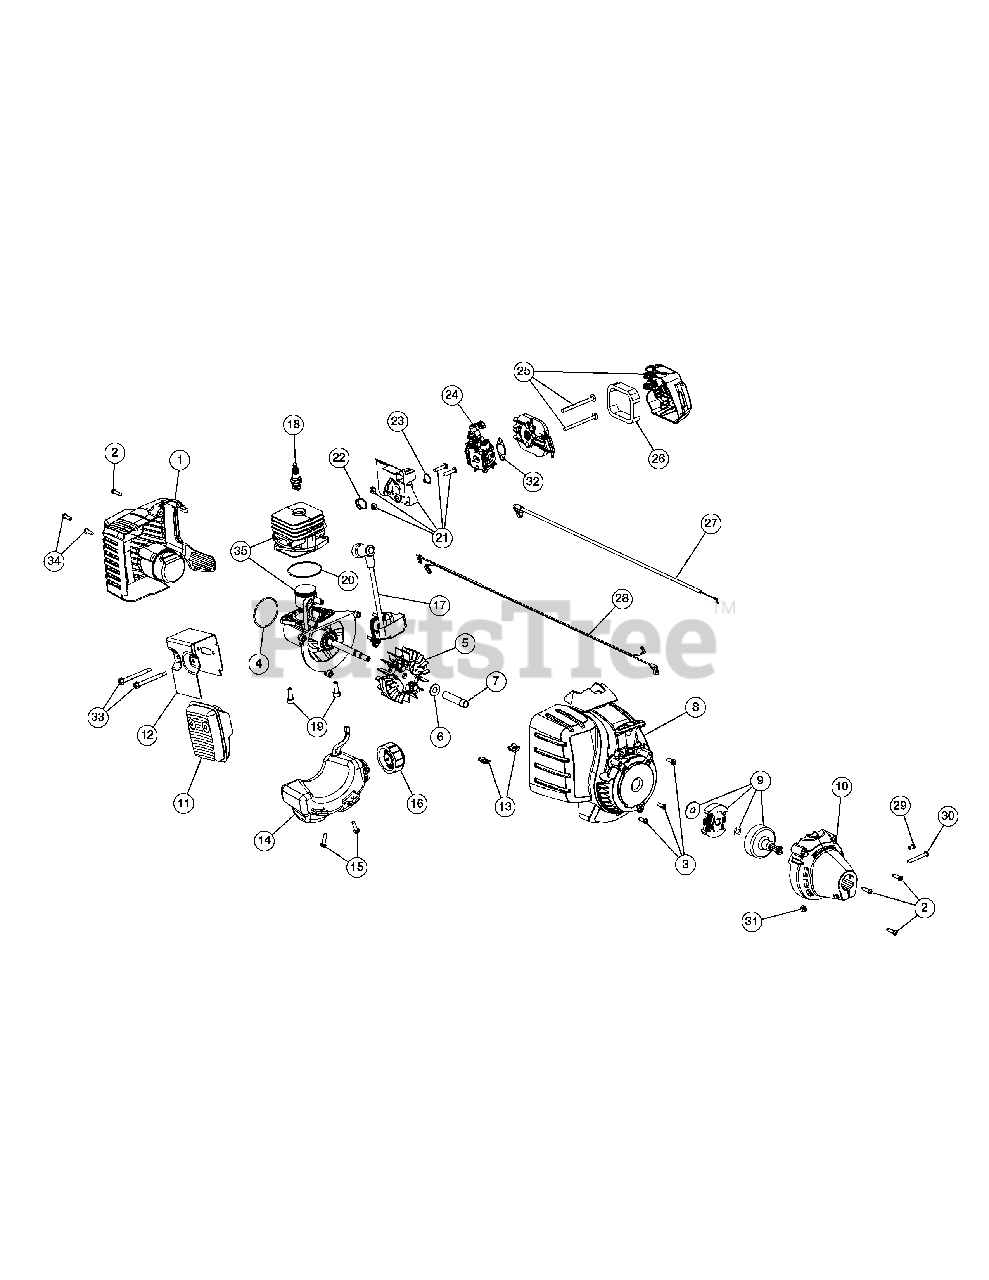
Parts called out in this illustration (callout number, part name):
1	Rear Cover Assembly (Incl. 2 & 34)
2	Cover Screw
3	Housing Screw
4	O-Ring
5	Flywheel Assembly
6	Washer
7	Spacer
8	Starter Housing (Incl. 3 & 13)
9	Clutch Assembly
10	Clutch Cover (Incl. 2)
11	Muffler Assembly (Incl. 12 & 33)
12	Muffler Gasket
13	U-shaped Nut
14	Fuel Tank Assembly (Incl. 15 & 16)
15	Tank Screw
16	Fuel Cap
17	Module Assembly
18	Spark Plug
19	Crankcase Bolt
20	Crankcase O-Ring
21	Insulator Assembly (Incl. 22 & 23)
22	Insulator O-Ring
23	Carburetor O-Ring
24	Carburetor
25	Aircleaner Cover Assembly (Incl. 26)
26	Aircleaner Filter
27	Throttle Cable
28	Lead Wires
29	Anti-rotation Screw
30	Clamp Screw
31	Clamp Nut
32	Air Cleaner Gasket
33	Muffler Screw
34	Rear Housing Screw
35	Short Block Assembly (Incl. 4 - 7 & 17 - 20)
